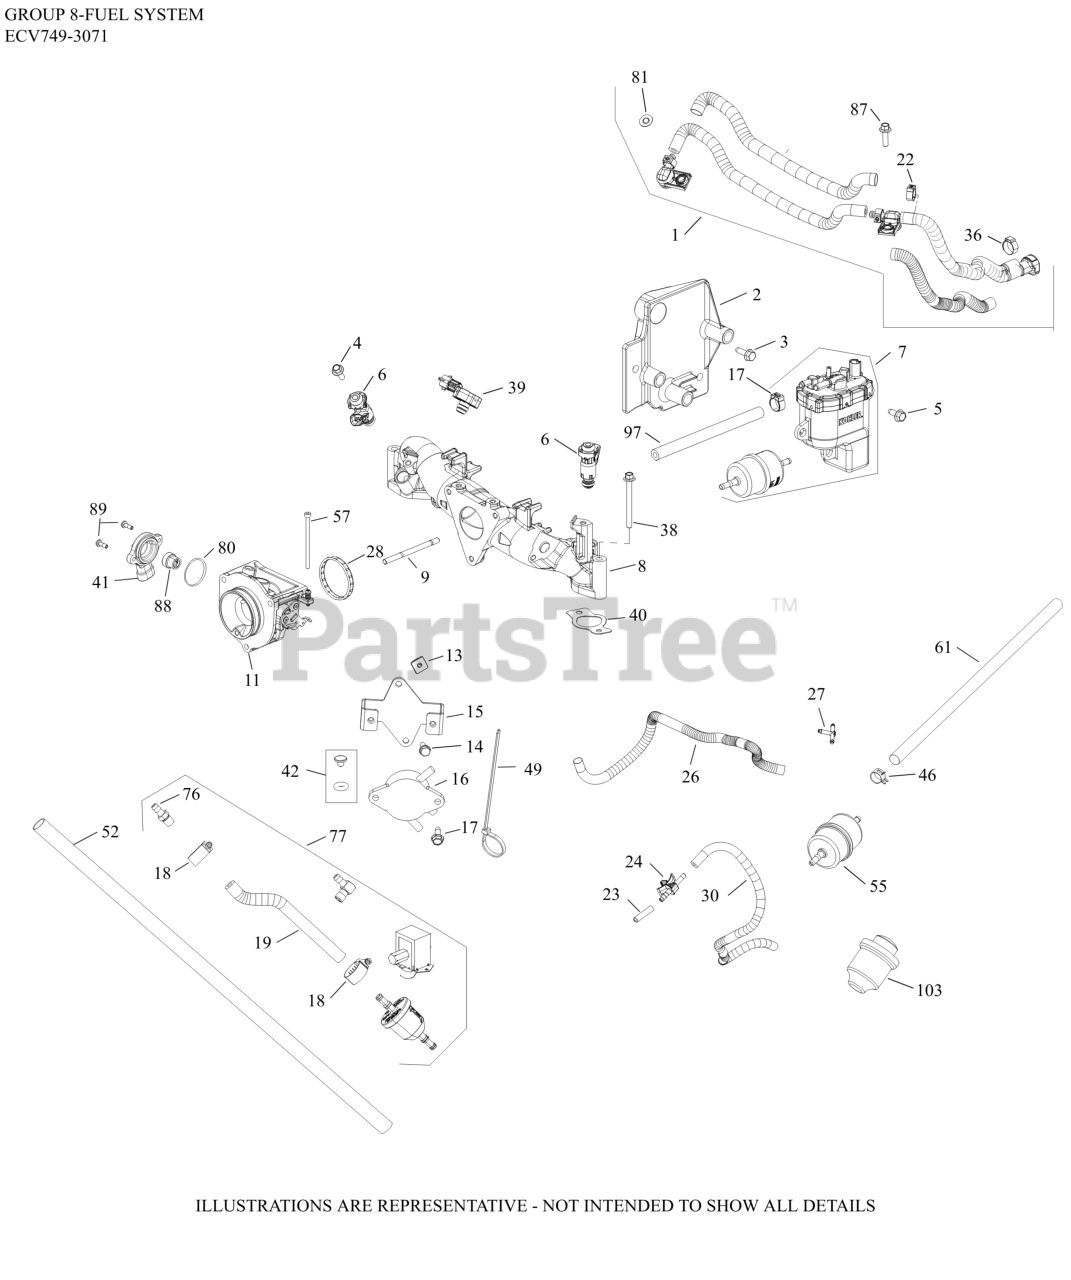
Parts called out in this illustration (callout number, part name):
1	FUEL HOSE ASSY(ECV,FCV,EZT,EKT,PCH,PCV)
2	KIT,BAFFLE, FUEL MODULE
3	SCREW, THREAD FORMING
5	SCREW, FLG M6X1.0X16
6	INJECTOR, FUEL
7	FUEL PUMP
7	KIT,FP MODULE (ECH/ECV 440,630,940)
8	KIT, MANIFOLD
9	STUD,M6X1.0X84
11	BODY, THROTTLE ASM (30)
13	NUT, PLASTIC - BLACK
14	SCREW, TAP M6X1.7X18
15	BRACKET, FUEL PUMP MOUNTING
16	PUMP, FUEL
17	SCREW, THREAD FORMING
18	CLAMP, HOSE (KM)-USE 25 237 31-S
19	HOSE,LW PERM.FUEL 24.00"-USE 25 111 81-S
22	CLAMP, OETIKER
23	CAP, MASKING
24	CONNECTOR, EVAPORATIVE
26	SLEEVE, ANTI-ABRASION
27	TEE CONNECTOR
28	O-RING, THROTTLE BODY
30	HOSE, EVAPORATIVE (15.0)
36	CLAMP, HOSE
38	SCREW, FLG M6X1.0X60
39	SENSOR, T-MAP
40	GASKET, INTAKE MANIFOLD-USE 24 041 79-S
41	SENSOR, THROTTLE POSITION
42	KIT, FUEL INJECTOR O-RING
46	SPRING CLAMP, HOSE
52	SLEEVE, HEAT REFLECTIVE
55	FILTER, FUEL
57	SCREW, HEX SOCKET HEAD CAP
61	SLEEVE, ANTI ABRASION -USE 25 431 12-S
80	O-RING, TPS SENSOR
81	CLIP, RETAINER
87	SCREW, FLG M6x1.0x20
88	MAGNET ASSEMBLY, TPS
97	HOSE, FUEL LOW-PERMEATION
103	KIT, AIR FILTER SENSOR
